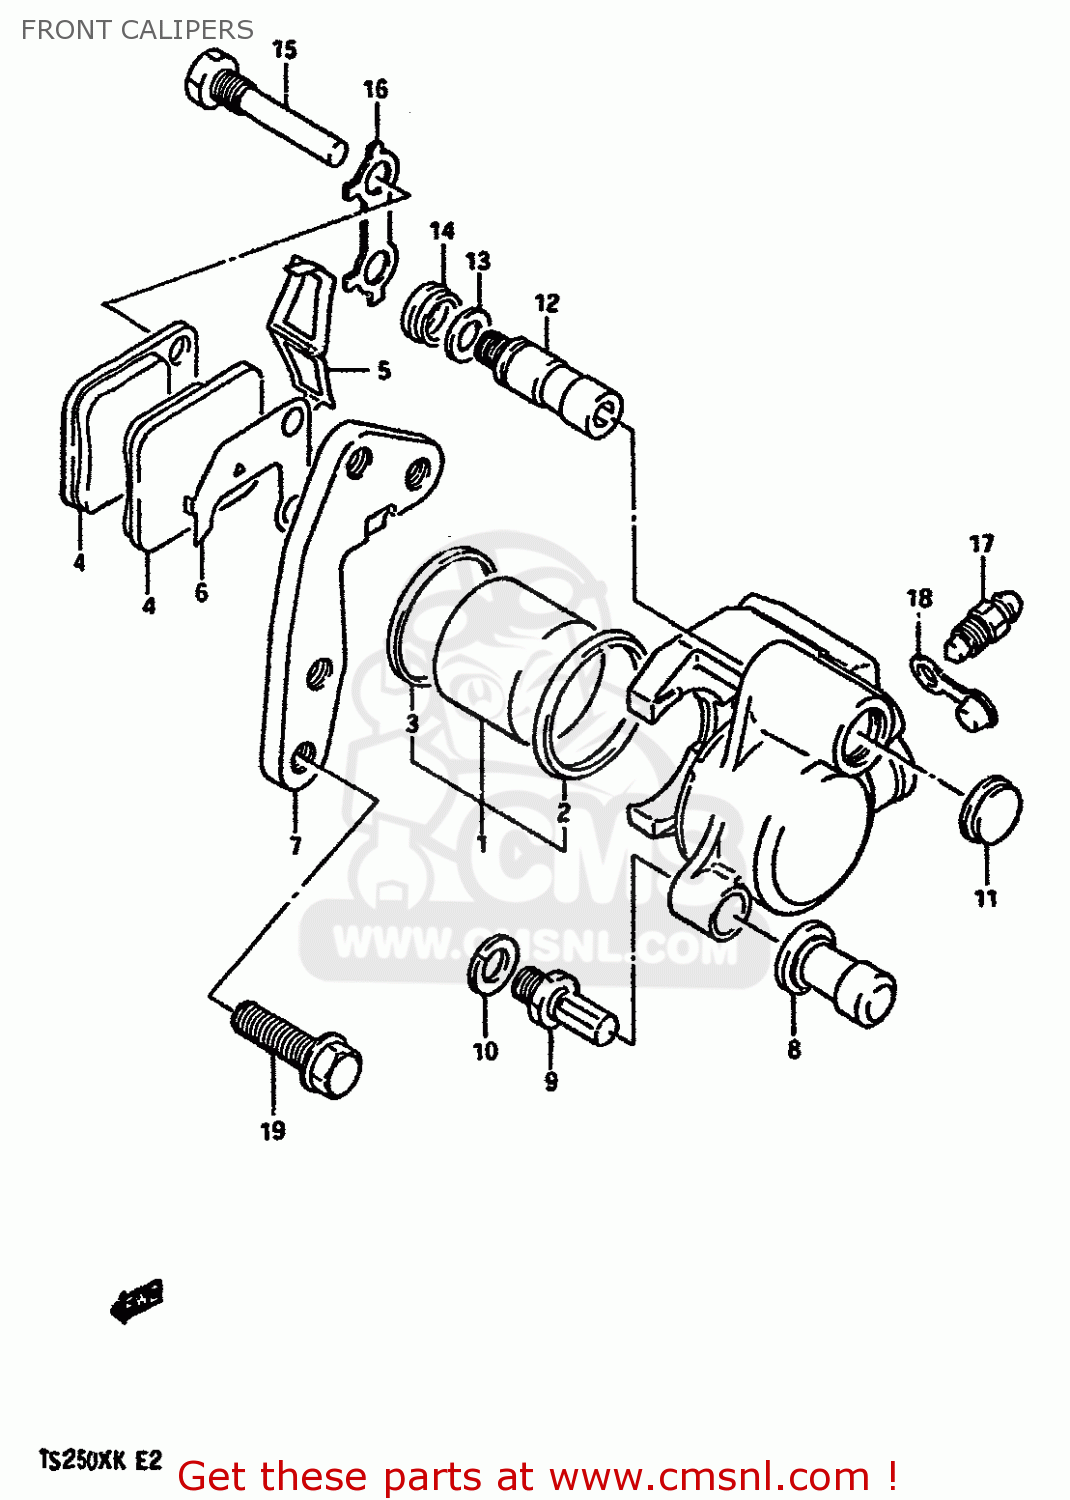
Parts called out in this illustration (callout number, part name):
1	PISTON SET,CALIPERS
2	SEAL,PISTON
3	BOOT,PISTON
4	PAD
5	SPRING,PAD
6	SHIM
7	BRACKET
8	BOOT
9	BOLT,PIN
10	WASHER,WAVE
11	DUST SEAL
12	PIN,SLIDE
13	SPRING,FRICTION
14	BOOT,PIN
15	PIN,HANGER
16	WASHER
17	BLEEDER
18	CAP,BLEEDER
19	BOLT
